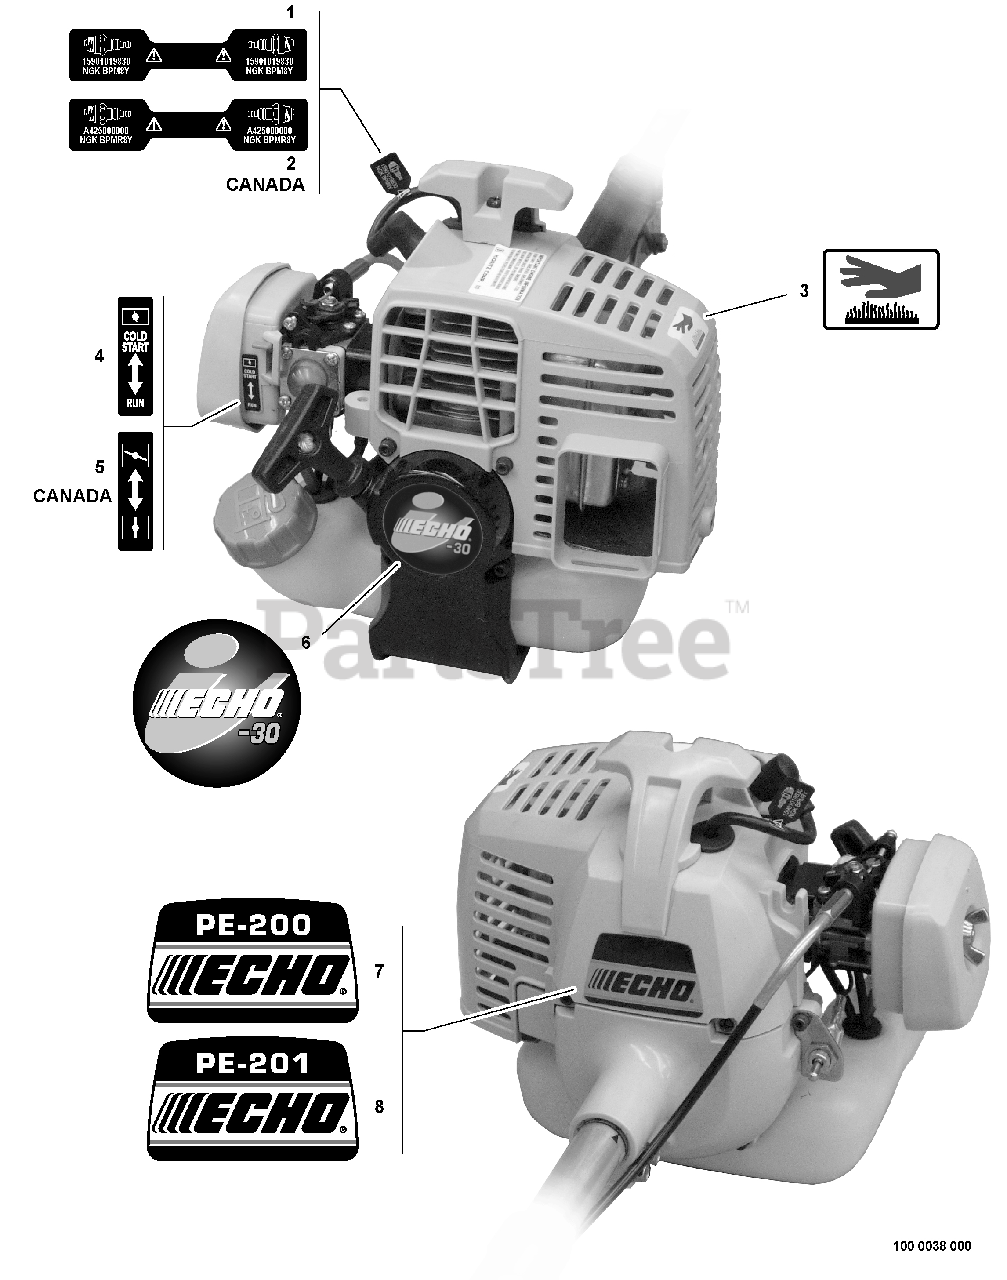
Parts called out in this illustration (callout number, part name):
1	LABEL - SPARK PLUG -- BPM-8Y
2	LABEL - SPARK PLUG -- BPMR-8Y
3	LABEL - HOT SURFACE
4	LABEL - CHOKE
5	LABEL - CHOKE
6	LABEL - ECHO -- i-30
7	LABEL - MODEL PE-200
8	LABEL - MODEL PE-201
